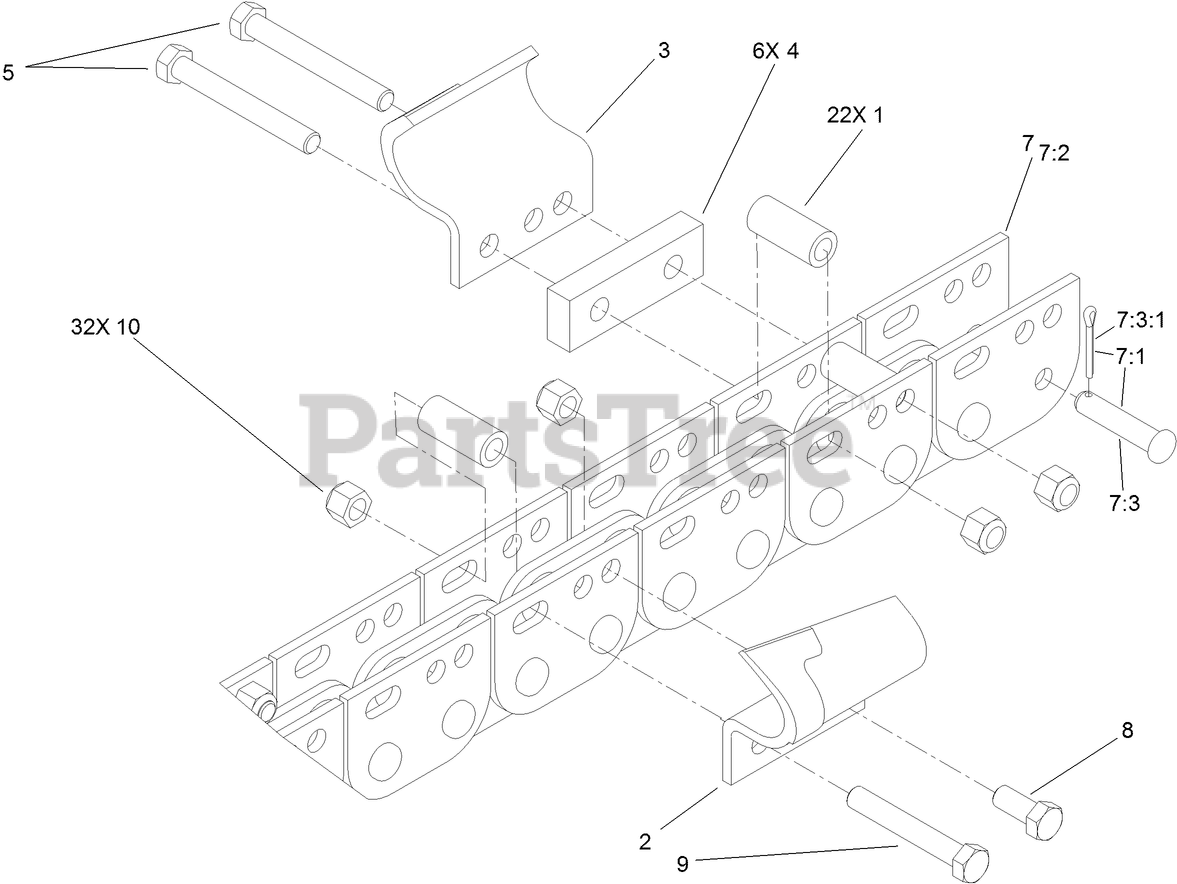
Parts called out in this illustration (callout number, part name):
1	SPACER-TUBE
2	TOOTH-SOIL, LH
3	TOOTH-SOIL, RH
4	SPACER-CUT, 5 INCH
5	SCREW-HH
7	CHAIN-BARE, 32 STATION
7:1	PIN-CONNECTING
7:2	LINK REPAIR KIT
7:3	PIN-CONNECTING (61MM)
7:3:1	PIN-COTTER
9	SCREW-HH
10	NUT-HEX
